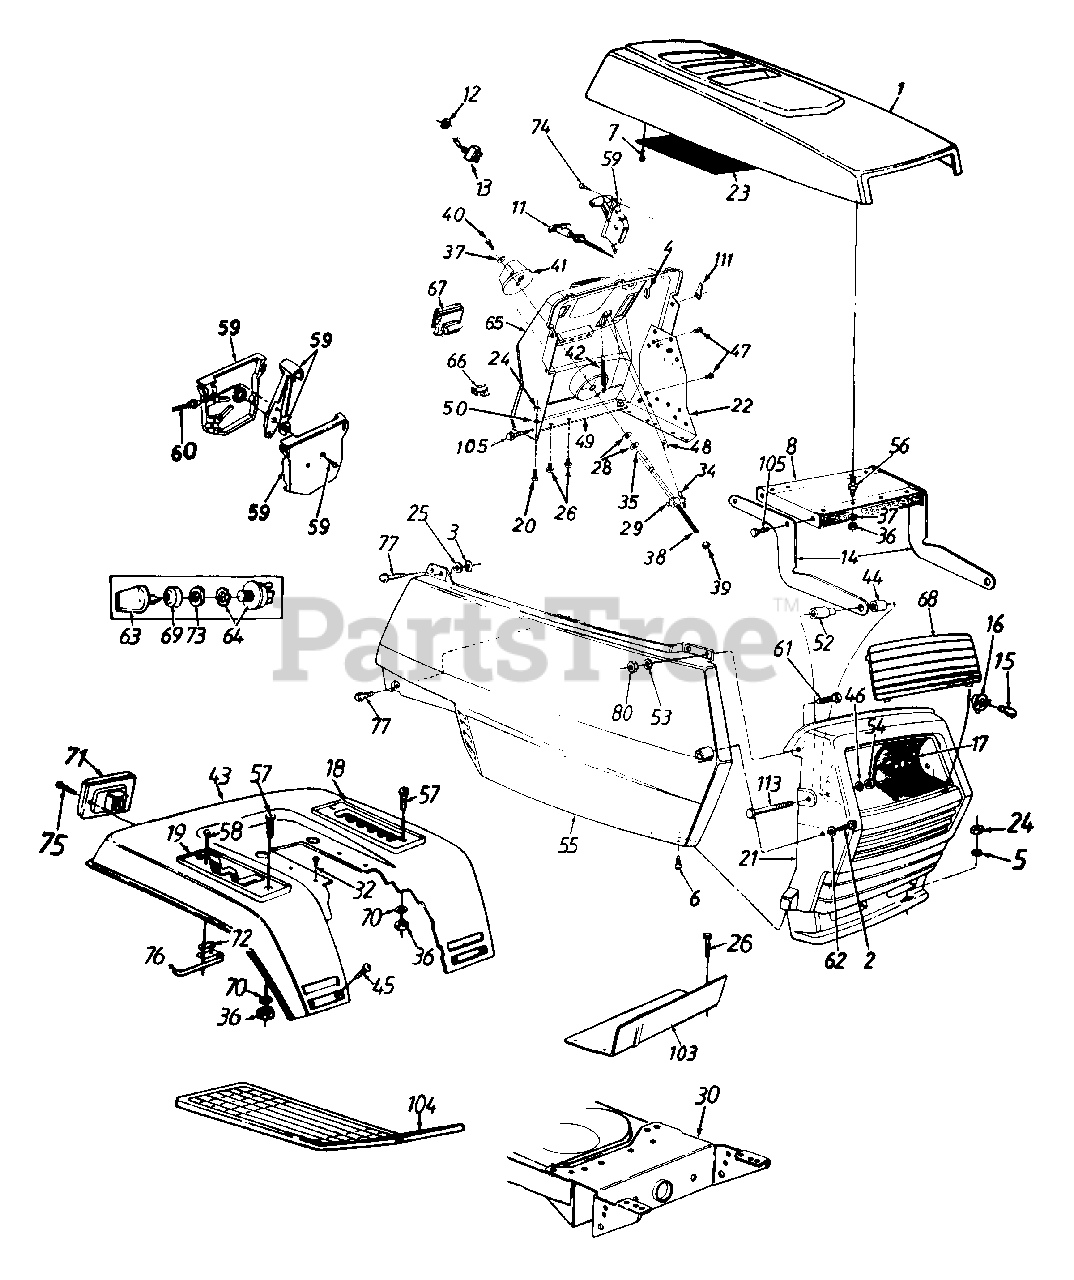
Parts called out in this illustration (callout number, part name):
1	Hood
2	Hex Wash. B-Tap Scr. 1/4 x .62" Lg.
3	Bolt Retainer 1/4" I.D.
4	Retainer Clip
5	Fl-Wash. .34" I.D. x 1"
6	Truss Mach. B-Tap Scr. #10 x .5" Lg.
7	Hex Wash. Hd. AB-Tap Scr. #8 x .5" Lg.
12	Hex Nut 1/2-27 Thd.
13	Toggle Switch
16	Twist Lock - Lamp Socket
17	Reflector - Headlight
18	Forward/Reverse Index Brkt.
19	7-Speed Selector Plate
20	Hex Bolt 5/16-18 x .75" Lg.
21	Grille
24	Hex Nut 5/16-18 Thd.
25	Fl-Wash. 1/4" I.D. x .93" O.D.
26	Hex Wash. Hd. B-Tap Scr. 5/16-18 x .5" Lg.
28	Fl-Wash. 3/8" I.D. x .875" O.D.
29	Adj. Ferrule 3/8-8 Thd.
32	Hex Wash. Hd. AB-Tap Scr. 5/16 x .75" Lg.
34	Hairpin Clip
35	"E"-Ring .375" Dia.
36	Hex Nut 1/4-20 Thd.
37	Bell-Wash. .265" I.D. x .75"
38	Adjustment Rod
39	Hex Nut 3/8-8 Twin Thd.
40	Hex Bolt 1/4-20 x .75" Lg.
41	Plastic Knob
42	Ext. Spring 3.21" Lg.
45	Carriage Bolt 1/4-20 x .50" Lg.
46	Fl-Wash. .328" I.D. x .68" O.D.
47	Hex Wash. Hd. Scr. 1/4-20 x .5" Lg.
48	Indicator Strip
52	Shld. Spacer .33" I.D.
53	Fl-Wash. .281" I.D. x .5" O.D.
54	Hex Cent. L-Nut 5/16-18 Thd.
55	Side Cover - R.H.
56	Double Ended Stud 1/4-20 Thd.
57	Truss Mach. Scr. 1/4-20 x .75" Lg.
58	Hex Wash Hd. AB-Tap Scr. #8 x .5" Lg.
59	Throttle Control Box Ass'y.
60	Throttle Control Wire 22" Lg.
61	Hex Bolt 1/4-20 x .62" Lg.
62	Fl-Wash..281" I.D. x .73" O.D.
64	Ignition Switch
65	Dash Panel
66	Light Switch
67	Ammeter
68	Lens
69	Ignition Switch Cap
70	L-Wash. 1/4" I.D.
71	Tail light
72	Insulator Nut Plate
73	Ignition Switch Nut
74	Truss Mach. AB-Tap Scr. #10 x .5" Lg.
75	Truss Hd. AB-Tap Scr. #6 x .62" Lg.
76	Reverse Safety Switch
77	Hex Wash. Hd. Tap Scr. 1/4 x .75" Lg.
80	Hex L-Nut 1/4-20 Thd.
105	Hex Tap Scr. 1/4-20 x .5" Lg.
111	Speed Nut 1/4-20 Thd.
113	Hex Bolt 5/16-18 x 2.75"
